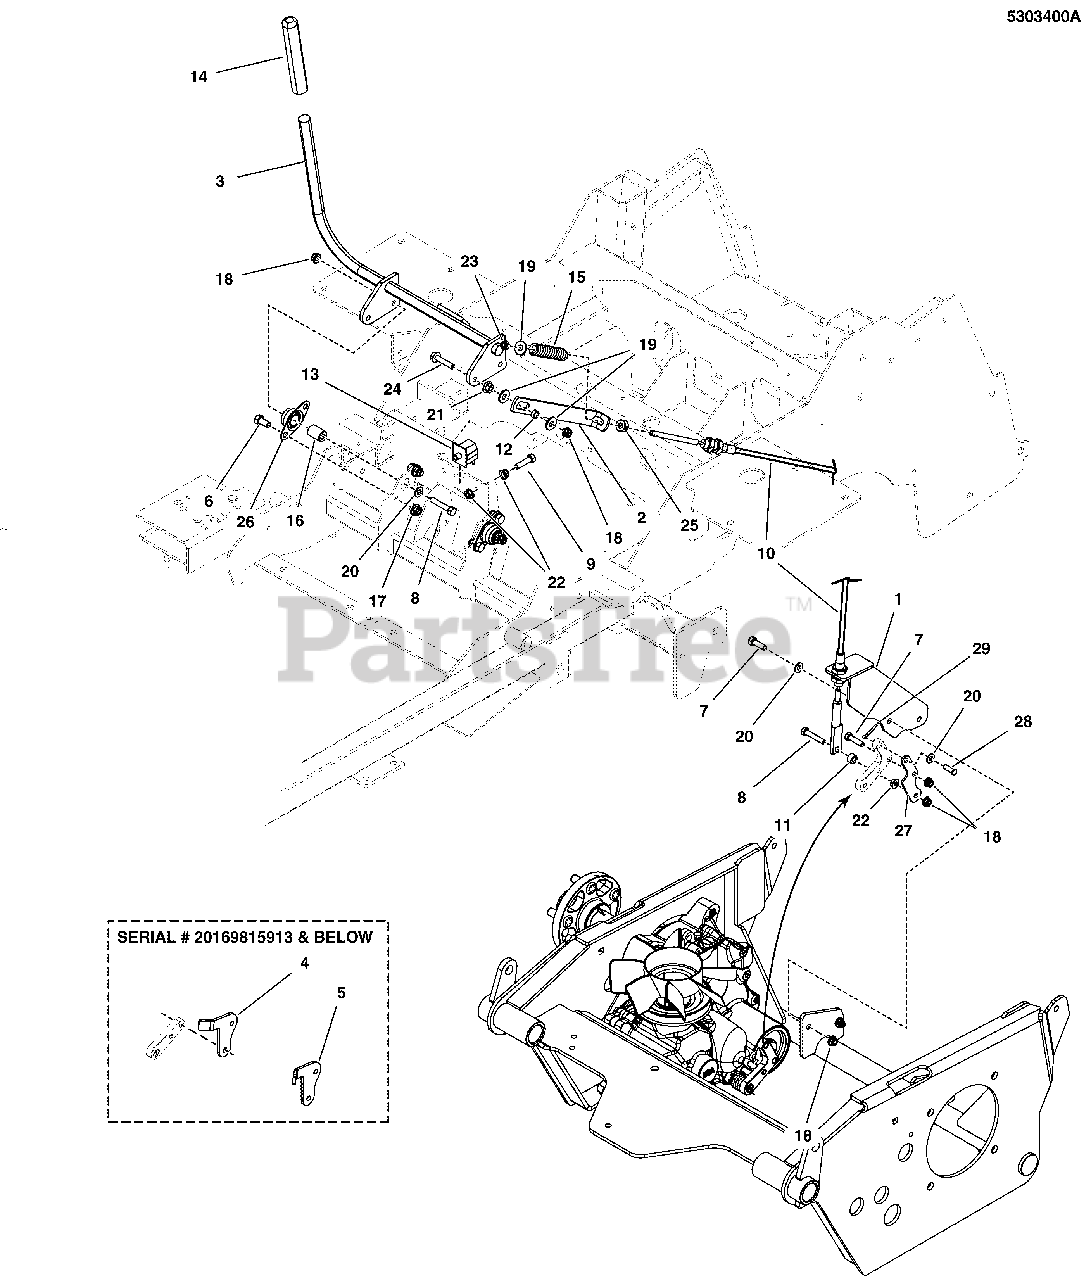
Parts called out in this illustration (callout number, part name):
1	BRACKET, Mounting
2	ARM, Link
3	WELD, BRAKE SHAFT, 2100 - BLK
4	PLATE, RIGH BRAKE, 2100 - BLK
5	PLATE, LEFT BRAKE, 2100 - BLK
6	BOLT, 3/8-16 X 3/4" GD5 CZ
7	BOLT, 5/16-18 X 1 GD5 CZ
8	BOLT, 5/16-18 X 1-3/4 GD5 CZ
9	BOLT, 5/16-18 X 1-1/4 GD5 CZ
10	CABLE, PARKING BRAKE, 32"
11	SPACER, .33 X .63 X .36, PM, CZ
12	SPACER, .33 X .50 X .25, PM, CZ
13	SWITCH, LOW PROF, NC/NO
14	GRIP, FOAM, 3/4 ID X 6 X .187
15	SPRING, COMP. 1/2 ID X .140 WIRE X 3.25
16	SPACER, .32 X .75 X 1.06, PM
17	NUT, 3/8-16 HEX NYLOCK FLANGE
18	NUT, 5/16-18 HEX NYLOCK FLANGE
19	WASHER, 5/16 USS
20	WASHER, 5/16" SAE
21	NUT, 5/16-18 HEX SERRATED FLANGE (LARGE)
22	NUT, 5/16-18 HEX SERRATED FLANGE (SMALL)
23	NUT, 5/16-24 HEX NYLON LOCK
24	BOLT, 5/16-18 X 1 1/2 FLANGE
25	COLLAR, 5/16 SET
26	BEARING, BRONZE FLANGE, 3/4
27	PLATE, BRAKE ARM, IS2100 - BLK
28	PIN, CLEVIS, 5/16 X 1, PLATED
29	PIN, COTTER, 1/8 X 3/4
